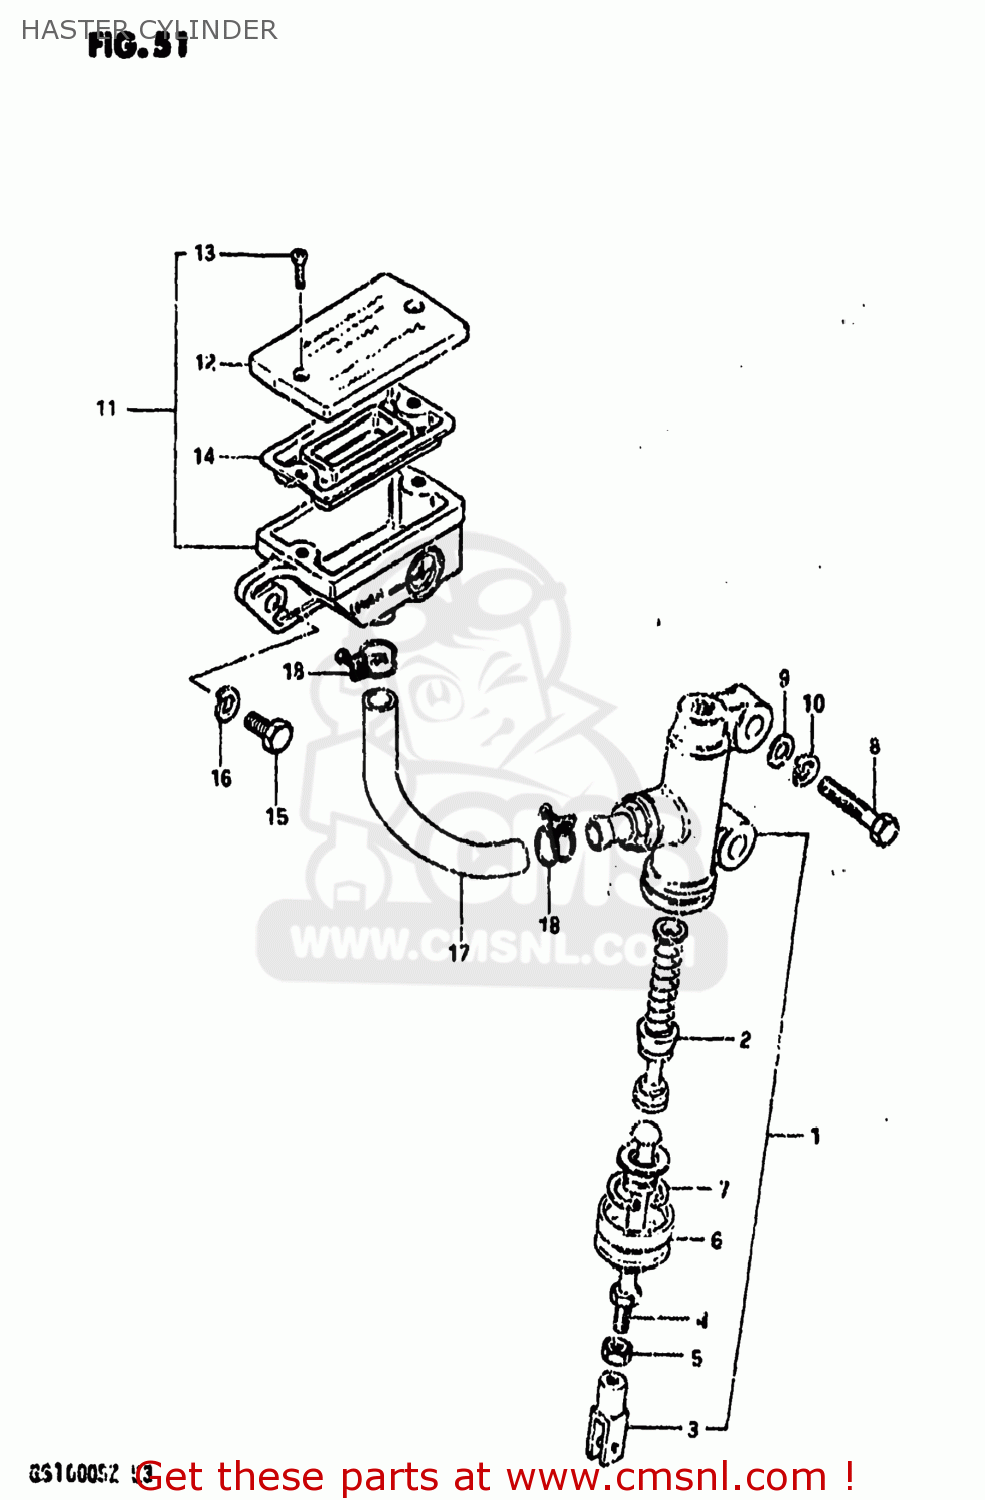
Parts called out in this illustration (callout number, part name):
1	CYLINDER ASSEMBLY,REAR MASTER
2	PISTON/CUP SET
3	YOKE
4	LOD,PUSH
5	NUT,MASTER CYLINDER
6	BOOT
7	CIRCLIP
8	BOLT (8X30)
9	WASHER
10	LOCK WASHER
11	TANK ASSEMBLY,RESERVOIR
12	CAP
13	SCREW
14	15
15	BOLT, UPPER
16	LOCK WASHER
17	HOSE,RESERVOIR TANK
18	CLAMP
